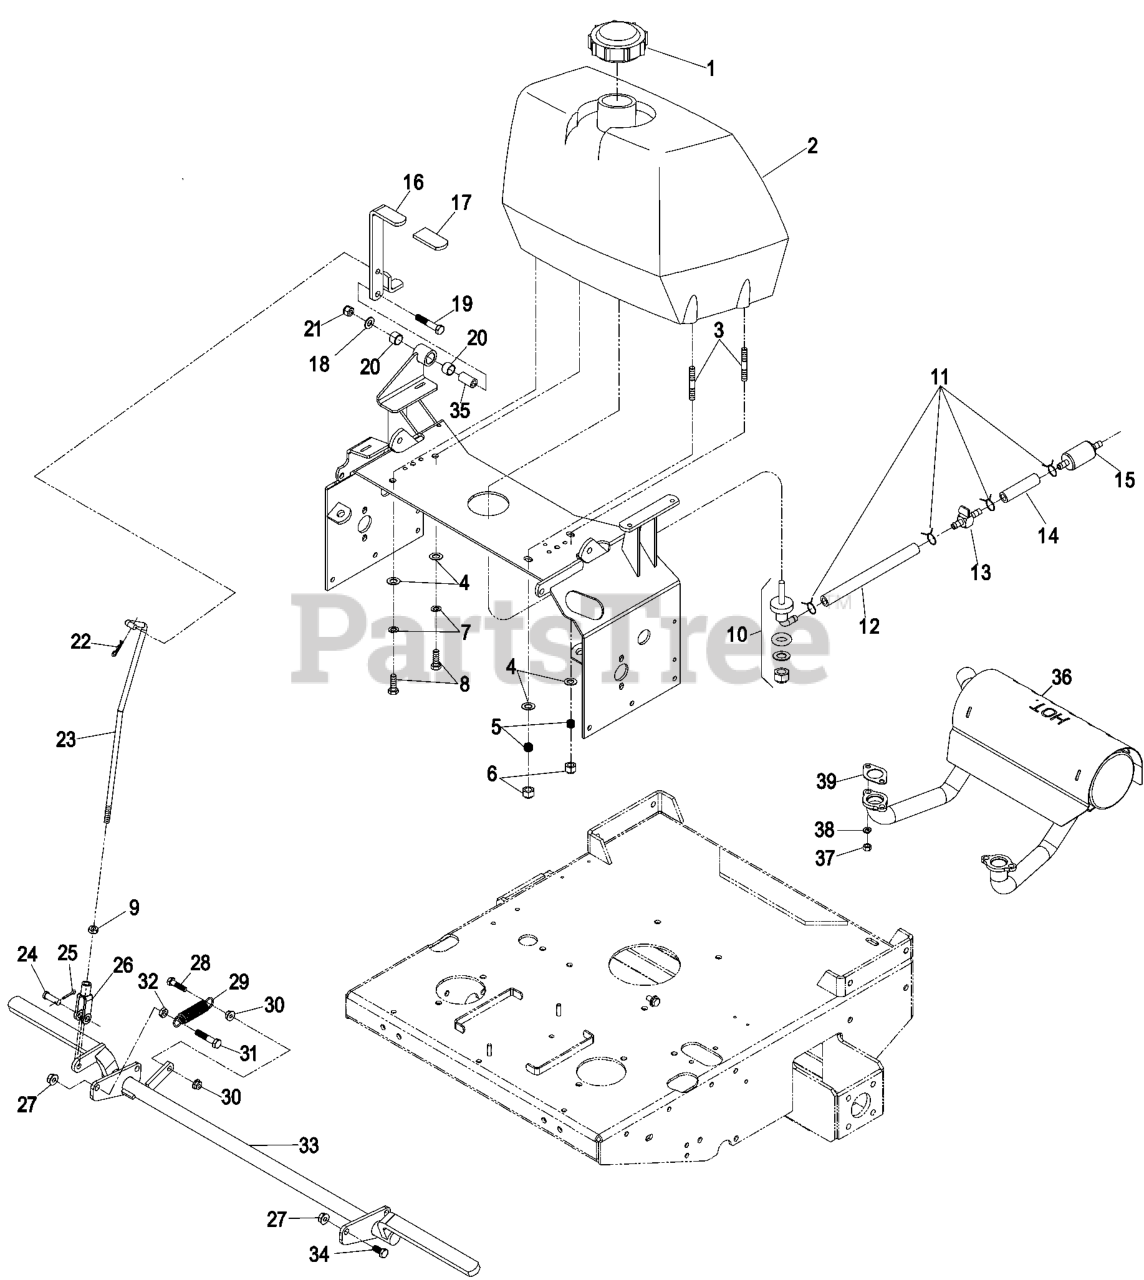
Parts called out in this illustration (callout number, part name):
1	CAP-FUEL, GAS
2	ASM,FUEL TANK W/B
3	STUD
4	WASHER-PLAIN
5	SPRING-TANK, FUEL
6	NUT-LOCK, NI
7	WASHER-LOCK
8	SCREW-HH
9	NUT-HJ
10	FITTING-FUEL, BULKHEAD
12	HOSE-FUEL
13	VALVE-FUEL
14	HOSE-FUEL
15	Part No 49019-7001 Fuel Filter
16	LEVER,PRK BRK W/DECALS
17	GRIP-LEVER
18	WASHER-FLAT
19	SCREW-HH
20	SLEEVE-BUSHING
21	NUT-LOCK, NI
22	PIN-COTTER
23	LINKAGE, PARK BRAKE
24	PIN-CLEVIS
25	PIN-COTTER
26	YOKE-LINKAGE, BRAKE
27	NUT-HHF, WHIZ
28	SCREW-HH
29	SPRING-IDLER
31	SCREW-HH
32	NUT-JAM
34	SCREW-HH
35	BUSHING-PIVOT
37	NUT
38	WASHER-LOCK
39	GASKET-EXHAUST
